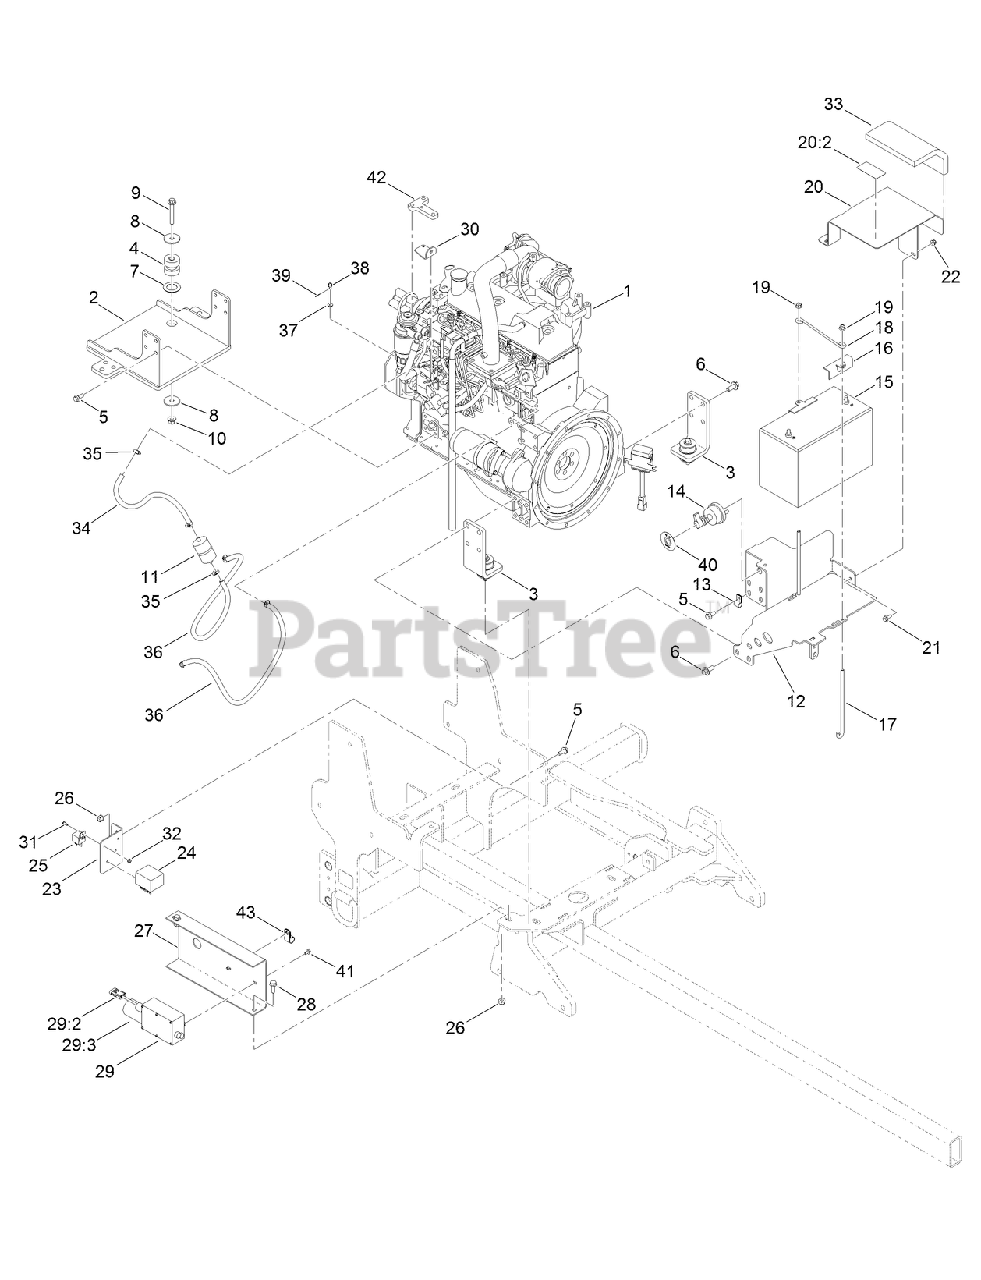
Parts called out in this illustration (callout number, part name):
1	ENGINE ASM
2	MOUNT-ENGINE AND RADIATOR
3	BRACKET-MOUNT, ENGINE
4	ISOLATOR-MOUNTING, UNIVERSAL
5	SCREW-HHF
6	SCREW-HHF
7	SPACER-ISOLATOR
8	WASHER-FLAT
9	SCREW-HHF
10	NUT-LOCK, HHF
11	FILTER-INLINE FUEL
12	BRACKET-MOUNT, BATTERY
13	R-CLAMP
14	SWITCH-BATTERY (1000 AMP)
15	BATTERY (1000CCA, WET)
16	ANGLE-HOLDDOWN, BATTERY
17	BOLT-HOLDDOWN, BATTERY
18	BRACKET-HOLDDOWN, BATTERY
19	NUT-HF, NI
20	BATTERY SHIELD ASM
20:2	DECAL-WARNING, BATTERY
21	SCREW-HHF
22	NUT-LOCK, HHF
23	BRACKET-MOUNTING, RELAY
24	RELAY-CONTROL, ENGINE
25	RELAY-POWER
26	NUT-LOCK, NI
27	BRACKET-THROTTLE
28	SCREW-HHF
29	ACTUATOR-THROTTLE
29:2	CONNECTOR
29:3	MOTOR-ELECTRIC, 12V
30	BRACKET-THROTTLE
31	SCREW-HSBH
32	NUT-HF
33	SHIELD-HEAT
34	HOSE-FUEL
35	CLAMP-WORM
36	HOSE-FUEL
37	WASHER-FLAT
38	PIVOT-THROTTLE
39	PIN-COTTER
40	FACEPLATE-BATTERY, ON/OFF
41	SCREW-HHF
42	PLATE-MOUNT, FILTER
43	CLAMP-R
